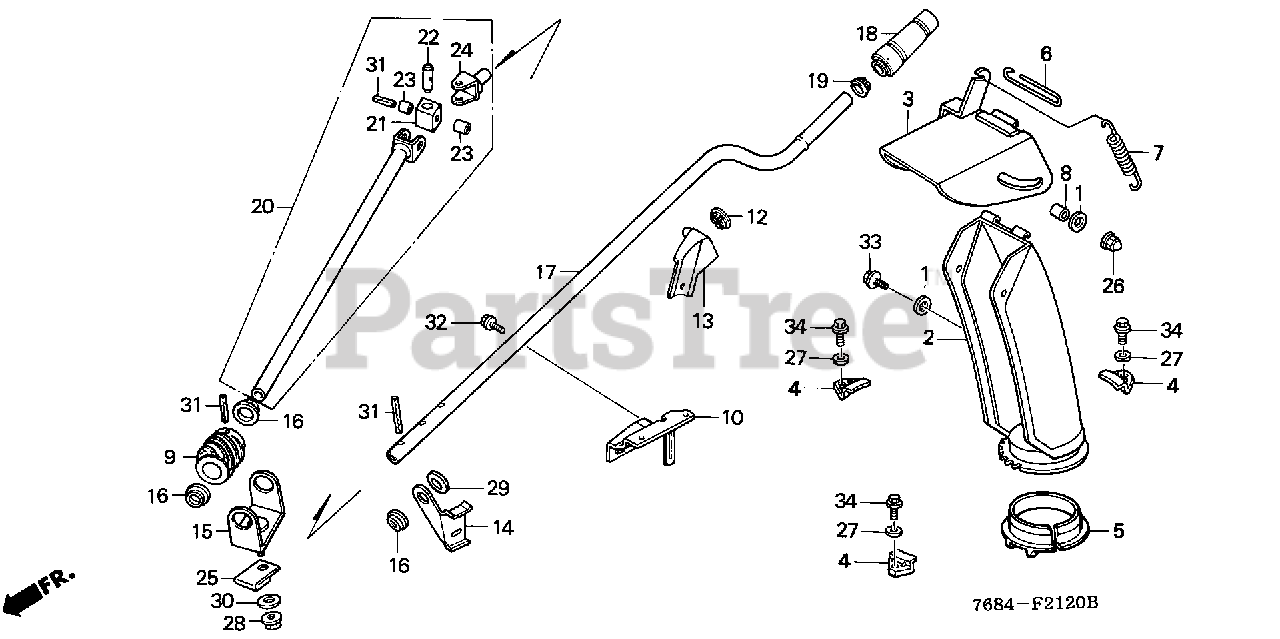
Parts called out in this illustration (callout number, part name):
1	WASHER, ACCELERATOR PEDAL
3	GUIDE, CHUTE (COO)
4	PLATE, CHUTE SETTING
5	BUSH, CHUTE
6	PIN, CHUTE GUIDE
7	SPRING, CHUTE
8	COLLAR, CHUTE GUIDE
9	GEAR, CHUTE DRIVE
10	HOLDER, HANDLE BRACKET
12	BUSH, CHUTE HANDLE
13	BRACKET A, CHUTE HANDLE
14	BRACKET B, CHUTE HANDLE
15	STAY, DRIVE GEAR
16	BUSH, DRIVE GEAR
17	HANDLE, CHUTE (UPPER)
18	GRIP, CHUTE HANDLE
19	BUSH A, CHUTE HANDLE
20	HANDLE, CHUTE (LOWER)
21	PIECE, JOINT
22	PIN A, JOINT
23	PIN B, JOINT
26	NUT, CAP (6MM)
27	WASHER, CHUTE SETTING
28	NUT, FLANGE (8MM)
29	WASHER, PLAIN (16MM)
30	WASHER, PLAIN (8MM)
31	PIN, SPRING (4X28)
32	BOLT, FLANGE (6X12)
33	BOLT, FLANGE (6X14)
34	BOLT, FLANGE (8X12)
